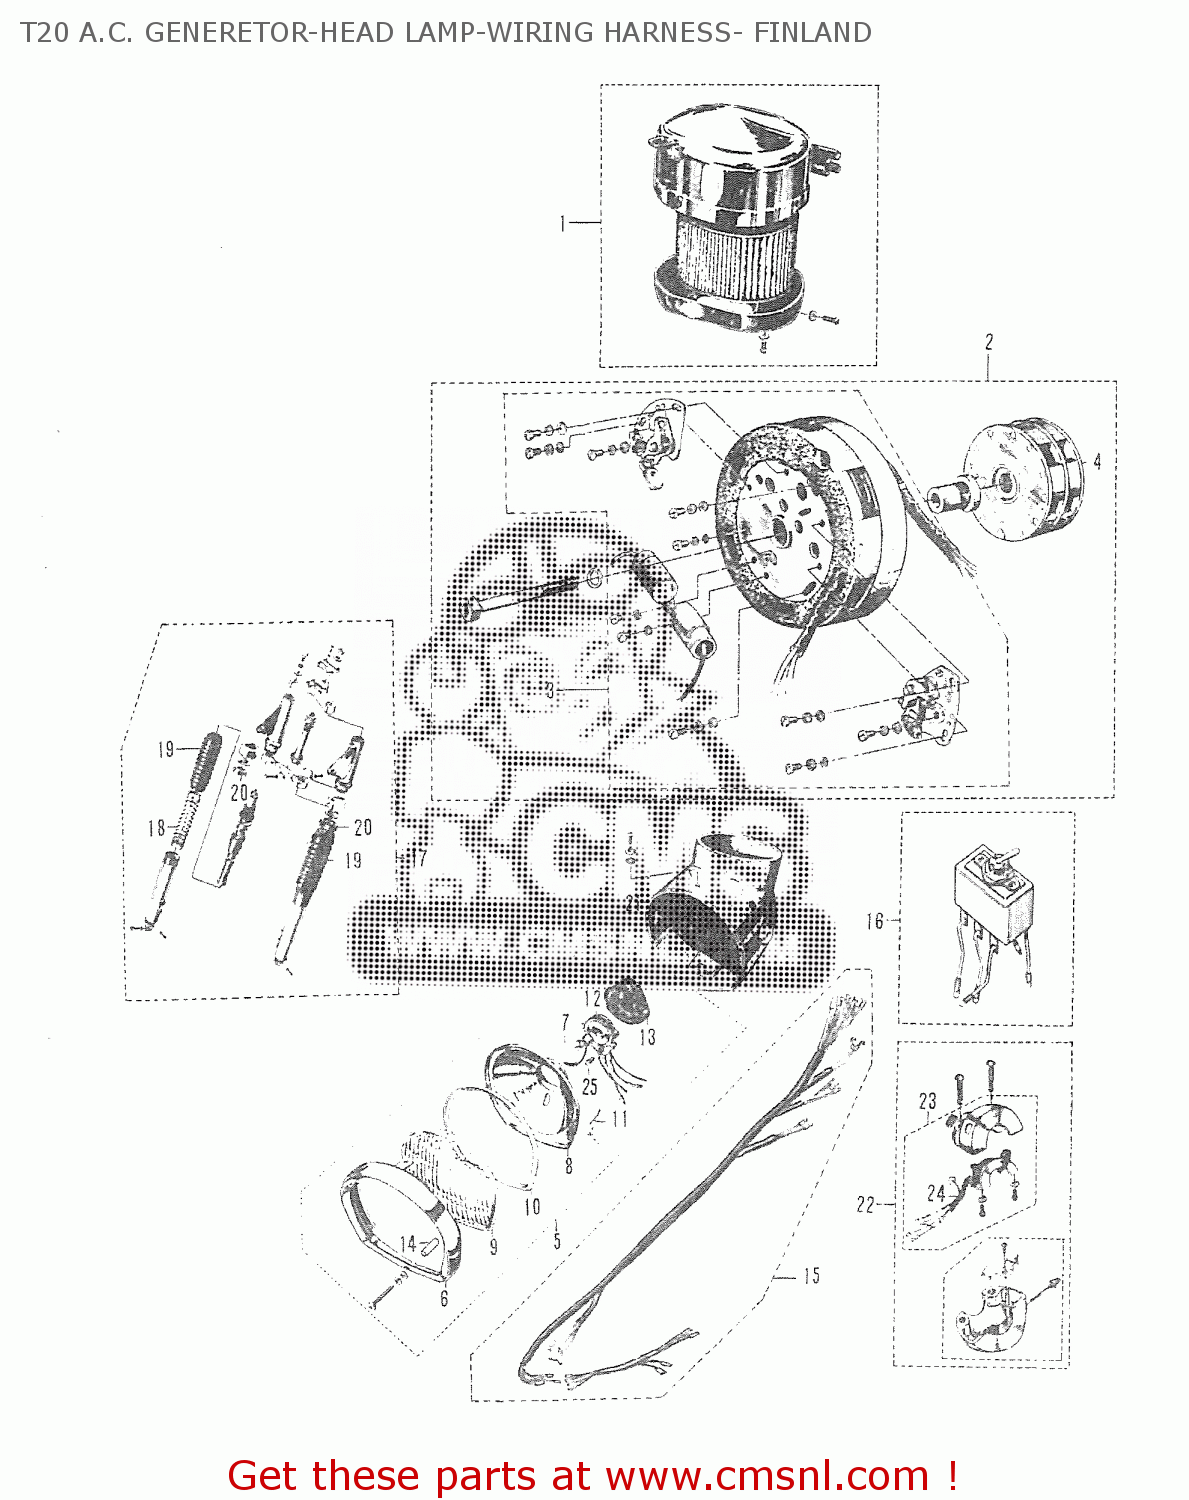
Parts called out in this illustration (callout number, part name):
1	AIR CLEANER ASS'Y
2	A.C. GENERATOR ASS'Y
3	STATOR ASS'Y
4	ROTOR
5	HEAD LAMP ASS'Y
6	HEAD LAMP RIM
7	HEAD LAMP BULB
8	HEAD LAMP REFLECTOR
9	HEAD LAMP LENS
10	HEAD LAMP LENS GASKET
11	SPRING,HEAD LA
12	HEAD LAMP BULB SOCKET
13	HEAD LAMP SOCKET RUBBER CAP
14	HEAD LAMP RIM FITTING SPACER
15	MAIN WIRING HARNESS ASS'Y
16	CITY LAMP SWITCH ASS'Y
17	FRONT FORK ASS'Y
18	SPRING,FRONT FORK
19	BOOT,SPRING COVER
20	BAND,FRONT FORK COVER
21	HEAD LAMP HOUSING
22	HANDLE SWITCH ASS'Y
23	HANDLE SWITCH UPPER COVER ASS'Y
24	WIRING HARNESS, SWITCH
25	BULB(12V3.4W,STANLEY,A72A)
